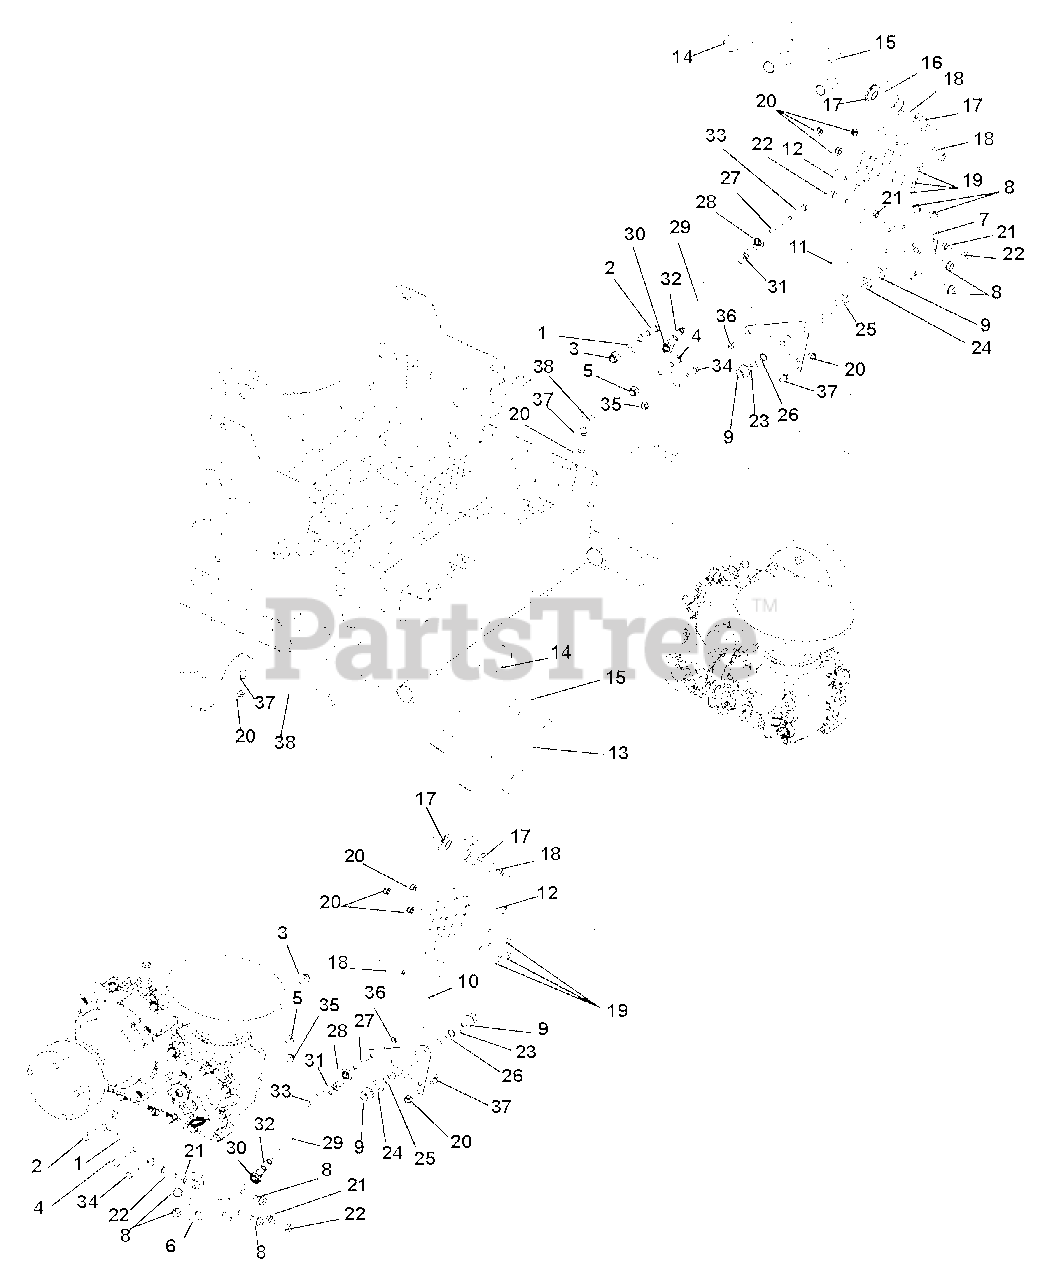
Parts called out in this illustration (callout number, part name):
1	Bracket, Control Mounting
2	Bolt, Hex .44-14 x 1.00 Grade 5
3	Nut, Locking-Nylon-Flange .44-14
4	Bolt, Hex .38-16 x 1.00 Grade 5
5	Nut, Locking-Nylon-Flange .38-16
6	Bracket, Right Hand Control Stop
7	Bracket, Left Hand Control Stop
8	Screw, Tapping .38-16 x .75 Hex Washer Head
9	Bushing, Flange .515 x .750 x .745 x 1.00 Nylon
10	Weldment, Right Hand Control Arm
11	Weldment, Left Hand Control Arm
12	Bushing, Eccentric .31 x .75 x .97
13	Handle Weldment Right Hand
14	Grip, Handlebar 1.00 x 1.38 x 11.3
15	Tube, .88ID x 1.00OD x 10.75
16	Handle Weldment Left Hand
17	Bushing, Flange .762 x 1.48 x .44 Nylon
18	Spacer .328 x .76 x 1.01
19	Bolt, Hex .31-18 x 1.75 Grade 5
20	Nut, Locking-Nylon-Flange .31-18
21	Nut, Hex-Jam .375-16
22	Bolt, Hex .38-16 x 1.25 Grade 5
23	Washer, Flat-Steel .520 x .810 x .033
24	Spacer .531 x 1.00 x .195
25	Wave Washer .531 x .781 x .125FH
26	Ring, Retaining-External .500 x .050
27	Eccentric
28	Alingaball, 5/16 Right Hand Thread
29	Rod, Steering
30	Alingaball, 5/16 Left Hand Thread
31	Nut, Jam .31-24
32	Nut, Jam Left Hand .31-24
33	Bolt, Hex .31-18 x 2.00 Grade 5
34	Bolt, Hex .31-18 x 1.00 Grade 5
35	Nut, Locking-Top-Flange .31-18
36	Nut, Locking-Center .31-18
37	Stud, Ball
38	Damper
